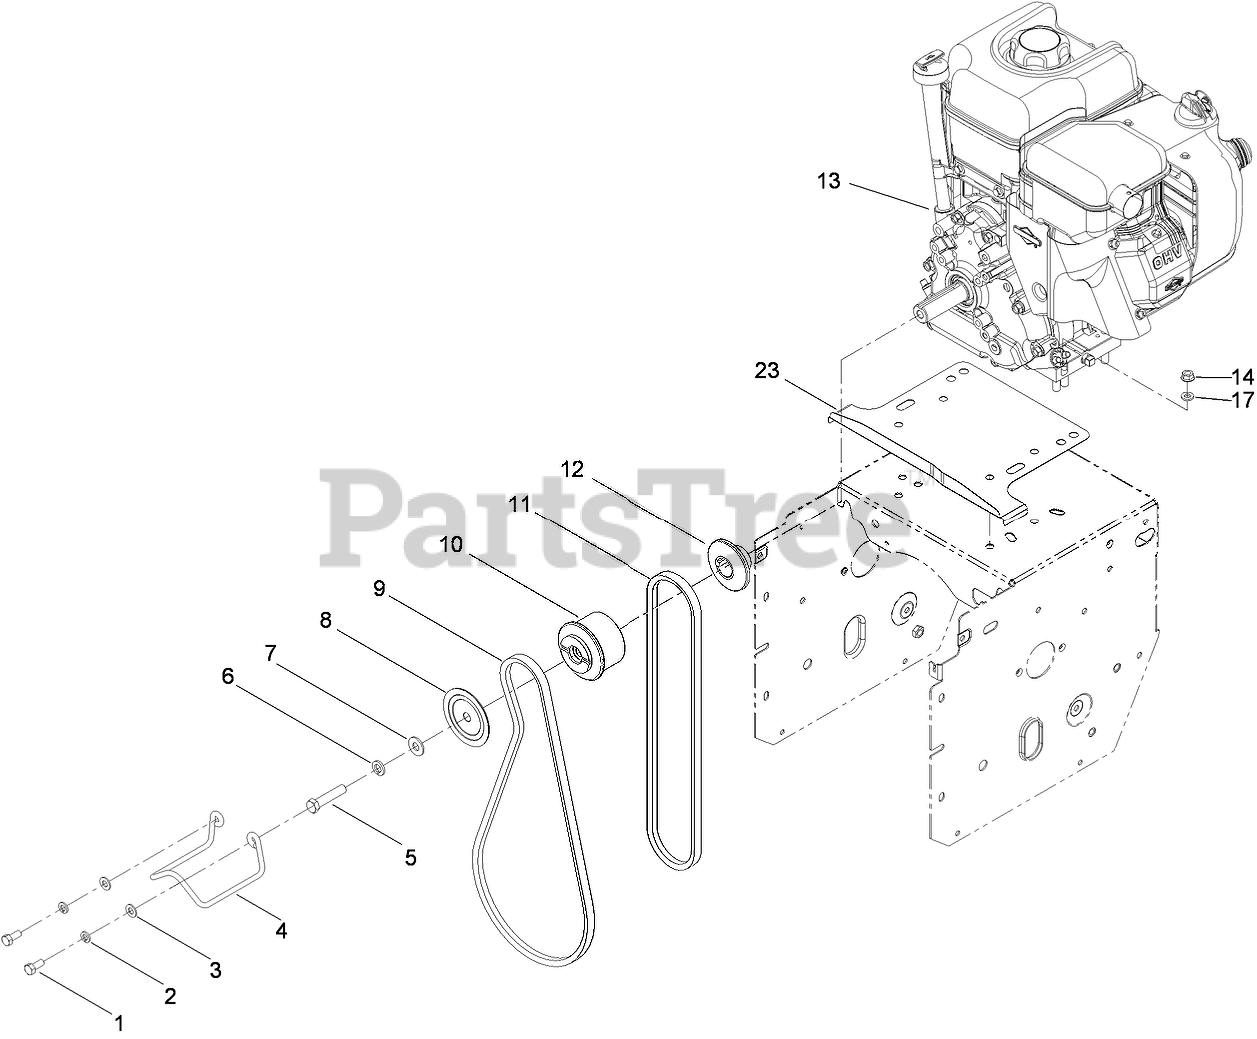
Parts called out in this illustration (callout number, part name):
1	SCREW-HH
2	WASHER-LOCK
3	WASHER-PLAIN
4	GUIDE-BELT
5	SCREW-HH
6	WASHER-LOCK
7	WASHER-FLAT
8	SHEAVE-HALF, IMPELLER
9	BELT-V
10	PULLEY-ENGINE, CENTER
11	V BELT-TRACTION
12	SHEAVE-HALF, TRACTION
14	NUT-HF
17	WASHER-FLAT
23	SHIELD-DRIVE
